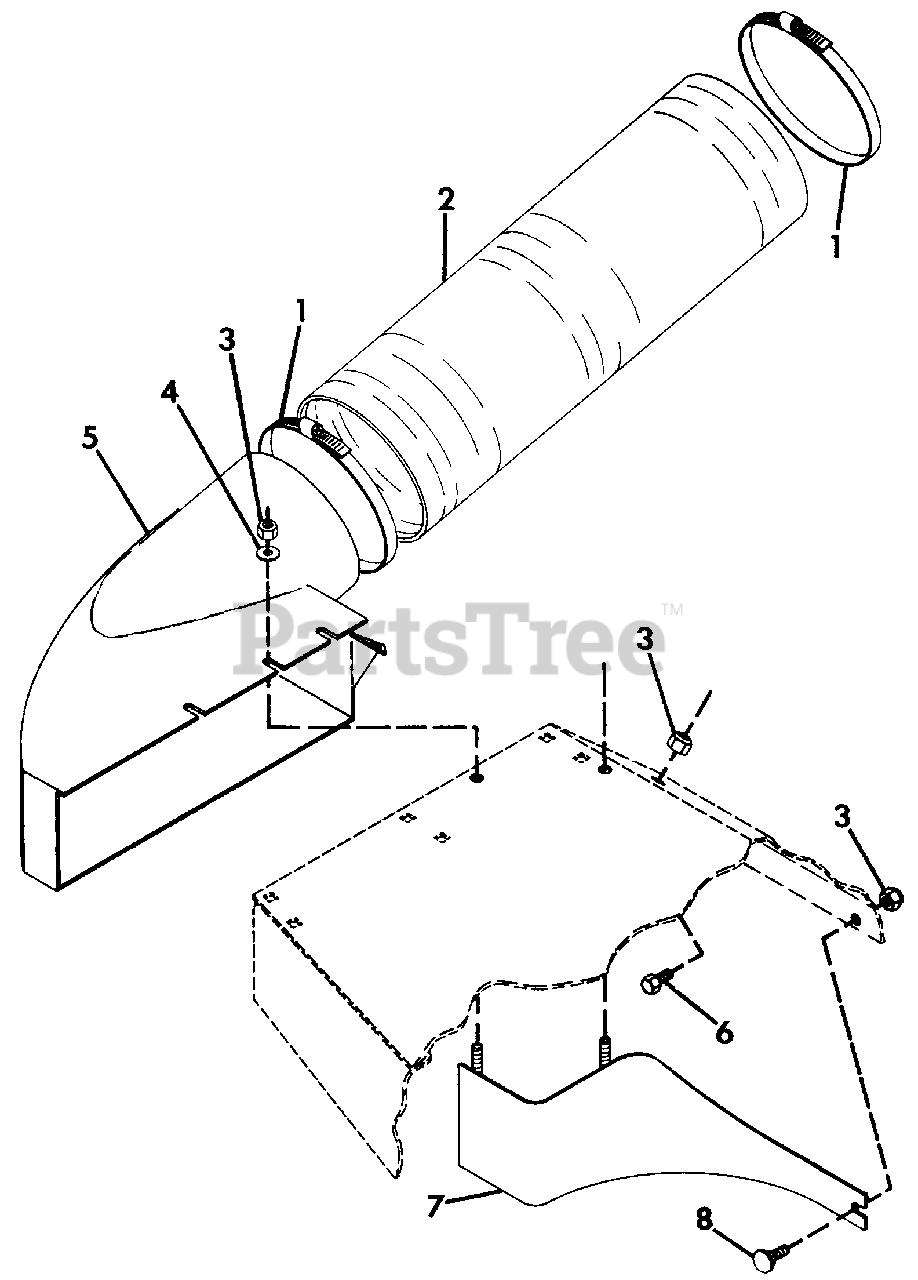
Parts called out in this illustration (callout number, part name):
1	CLAMP
2	HOSE, MOWER TO BLOWER
3	NUT, LOCK 3/8-16
4	WASHER, FLAT .406X.812X.065
5	CHUTE, 60" DISCHARGE
6	BOLT, HEX 3/8-16X1
7	WELDMENT, BAFFLE
8	BOLT, CARRIAGE 3/8-16X.75
